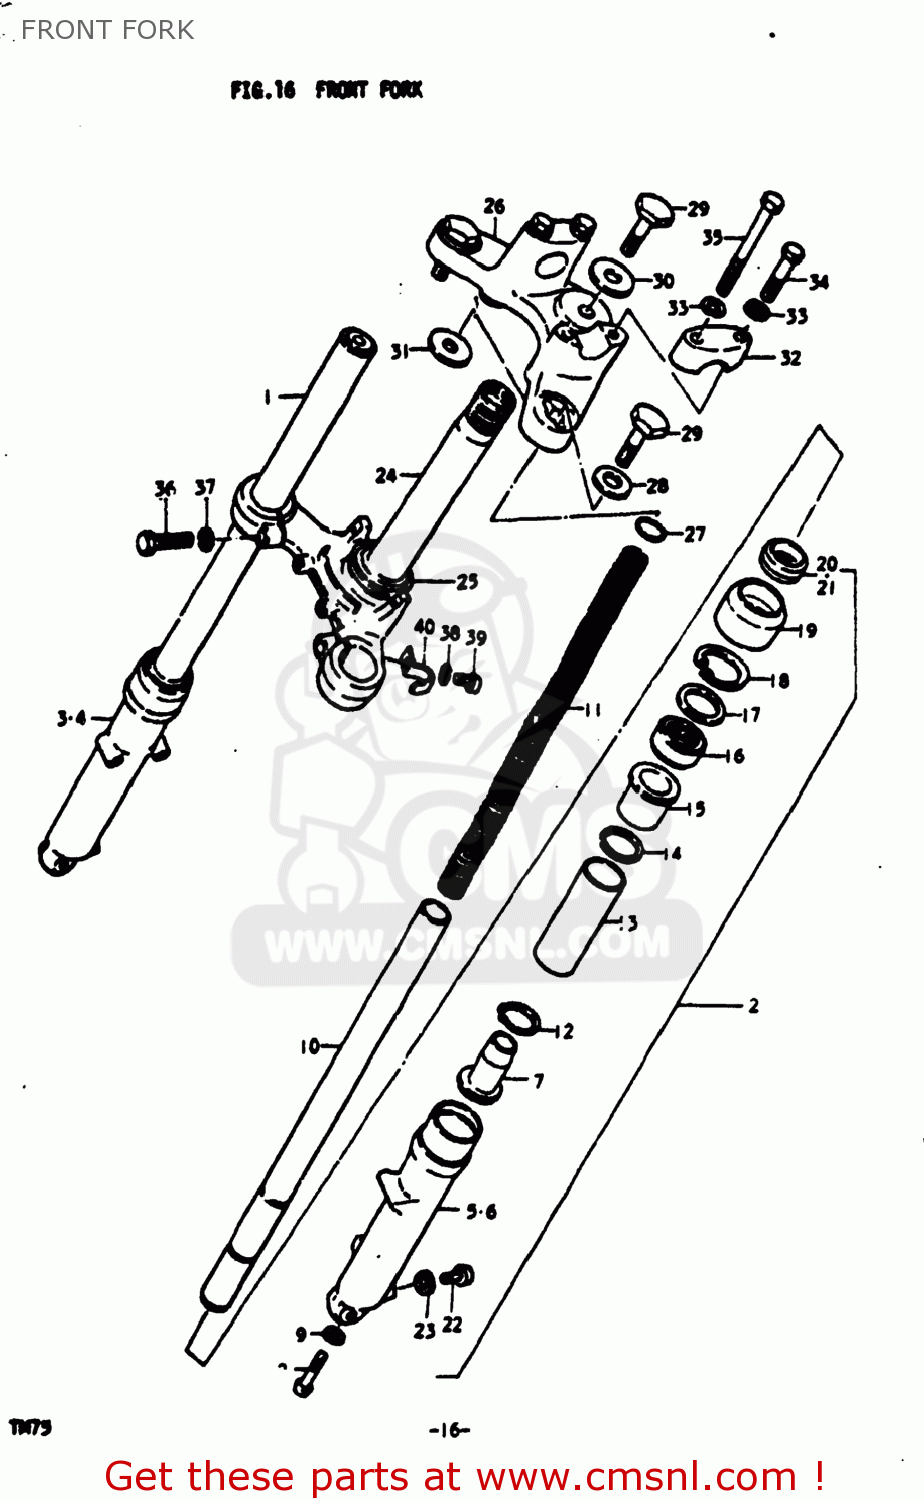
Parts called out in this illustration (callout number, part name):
1	DAMPER ASSEMBLY,RIGHT
2	DAMPER ASSEMBLY,LEFT
3	TUBE,OUTER,RIGHT
4	TUBE,OUTER,RIGHT
5	TUBE,OUTER,LEFT
6	TUBE,OUTER,LEFT
8	SCREW
9	GASKET (NAS)
11	SPRING
15	BUSHING,GUIDE
16	OIL SEAL,FRONT FORK
17	WASHER
18	CIRCLIP
19	BAND,FRONT FORK COVER
20	BOOT
21	BOOT
22	SCREW
23	GASKET (NAS)
24	STEM,STEERING
25	RACE,STEERING OUTER LWR
26	HEAD,STEERING STEM
27	O-RING,FORK INNER TUBE
28	WASHER
29	BOLT,FORK INNER TUBE
30	WASHER,STEERING STEM
31	WASHER,STEERING STEM
32	HOLDER,HANDLEBAR
33	LOCK WASHER
34	Bolt
35	BOLT
36	BOLT 10X30
37	LOCK WASHER
38	LOCK WASHER
39	SCREW
40	CLIP
